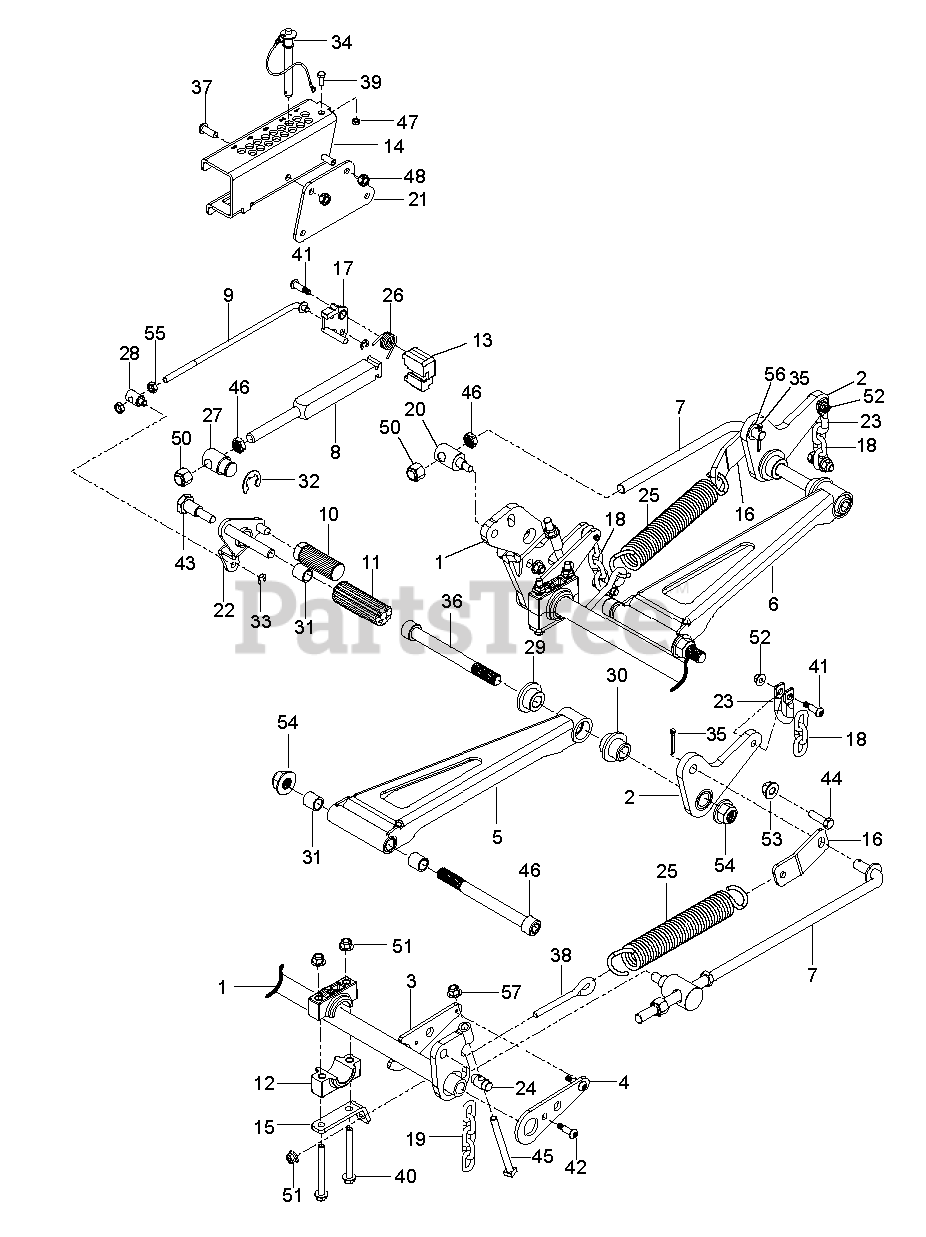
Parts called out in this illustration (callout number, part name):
1	SHAFT.WLDMNT.FRNT.DECK.LFT.PNT
2	KIT.ARM.BELLCRANK/BUSHINGS.LT
2	KIT.ARM.BELLCRANK/BUSHINGS.RT
3	ARM.DECK.LIFT.INNER.BLACK
4	ARM.LIFT.DECK.OUTER.POWER.BLK
5	ARM.DRAWBAR.LH
6	ARM.DRAWBAR.RH
7	ROD. CONNECTING
8	ROD.HEIGHT.GAUGE
9	ROD.RELEASE.CONNECTING.TOE
10	PEDAL, DECK HEIGHT
11	PAD, FOOT PEDAL
12	BLOCK, PILLOW
13	BLOCK.ROD.END
14	BRACKET.ADJUSTMENT.HEIGHT.ORNG
15	BRACKET.PILLOW.BLOCK.PNT.BLACK
16	LEVER.ASM.RR.LIFT.RH.HEAVYDUTY
16	BRACKET SPRING BLACK (X428)
16	LEVER.ASM.RR.LIFT.LH.HEAVYDUTY
17	KIT.LEVER.LOCK.W/BUSHING
18	LIFT CHAIN - 3 LINK
19	LIFT CHAIN
20	PIVOT.CONNECTING.ROD
21	PLATE.HEIGHT.GAUGE.MOUNT.PNT
22	LEVER ASSY TOE RELEASE
23	SHACKLE.CHAIN
24	SHAFT.TRUNNION.ATTACH
25	SPRING EXTENSION, DECK LIFT, H
26	SPRING.TORSION.RELEASE.LEVER
27	SWIVEL.HEIGHT.BAR
28	SWIVEL.TOP.RELEASE
29	BUSHING.DECK.INNER
30	BUSHING.DECK.OUTER
31	BUSHING, SLEEVE 3/4 X 1.0
32	E-RING 1"
33	E RING 3/8"
35	COTTER PIN 1/8 X 2
36	SCREW.SOCKET.HEADCP.3/4-10X7.5
37	SCREW.BUTTON.HEAD.CAP.3/8-16X1
38	EYE BOLT, 3/8 X 4"
39	HCS 1/4C X 3/4 HCS
40	SCREW.HHFS3/8-16X3.75.GR8
41	SCREW.SHOULDER.375X875.5/16-18
42	SCREW.SHLDR..375.5/16-18.88.LG
43	BOLT, SHOULDER
44	HCS 7/16C X 1 1/2
45	SCREW.HHC.7/16-14 X 4.50
46	NUT.HH.THIN.NYL.5/8-11 GR5
47	NUT.1/4-20.HEX.NYLOC.ZD
48	NUT 3/8C CENTERBLOCK
51	NUT 3/8-16 HEX FLG NYLOC ZD
52	5/16-18 NYLOC FLANGE NUT
53	NUT 7/16-14 HEX WHIZ LK
54	NUT.HEX.FLANGED.3/4-10.NYLOK
55	NUT 3/8-24 JAM
57	7/16-14 HEX NUT W/NYL RING ZD
57	Nuts
